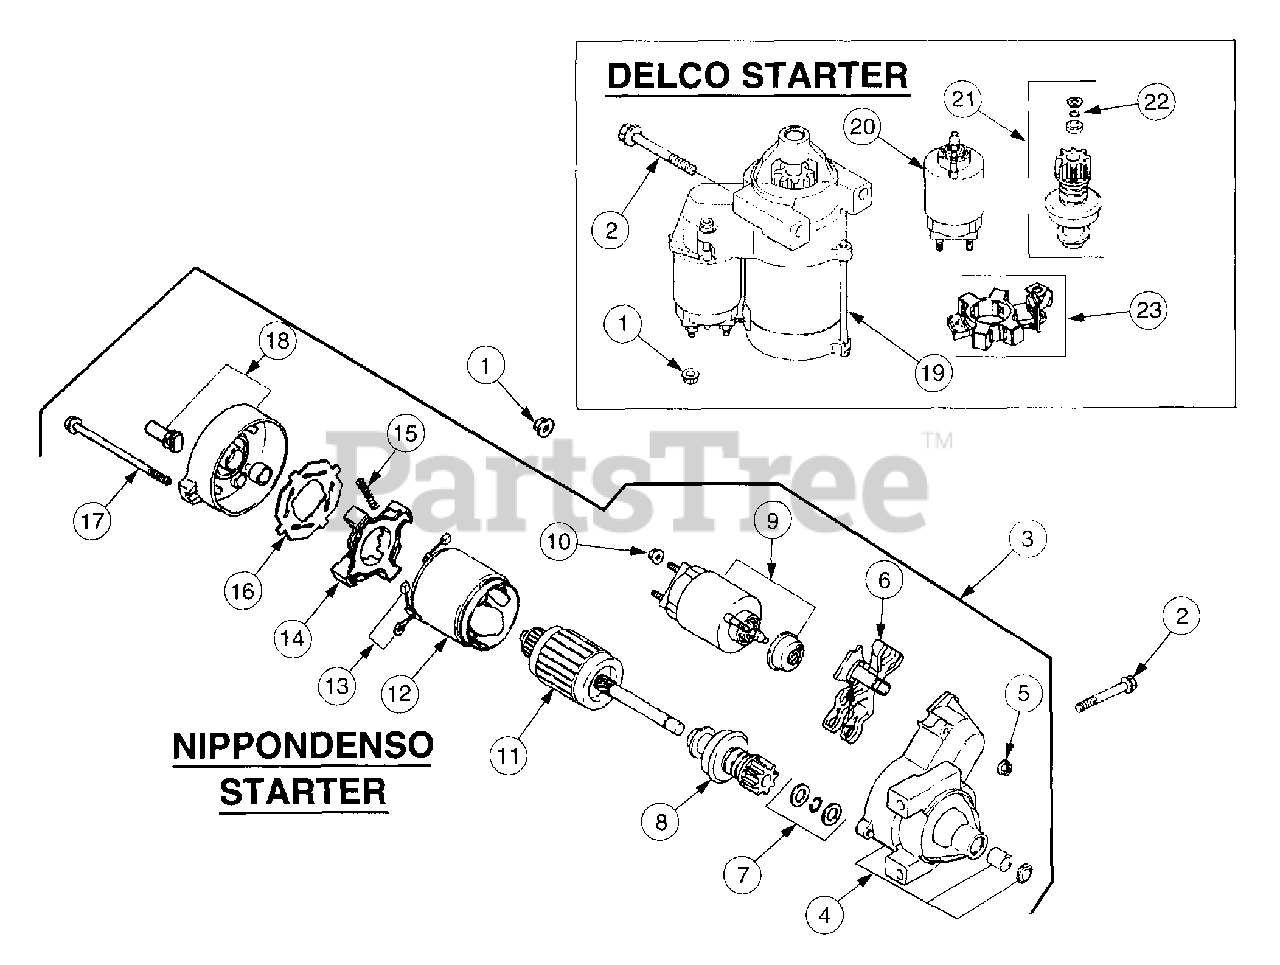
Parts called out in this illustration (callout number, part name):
1	Nut, Hex Flange M8 x 1.25
2	Screw, Hex Flange M8 x 1.25 x 80
3	Starter Assembly, Nippondenso
4	Drive, End Cap
5	Nut, Starter
6	Lever, Starter Drive
7	Kit, Starter Repair
8	Drive, Pinion
10	Nut, Starter
11	Armature, Starter
13	Kit, Brush and Spring
14	Holder, Brush
15	Spring, Brush
18	Commutator, End Cap
19	Starter assembly, solenoid shift (Delco)
20	Kit, solenoid
21	Kit, Pinion Drive
22	Ring, Retainer
